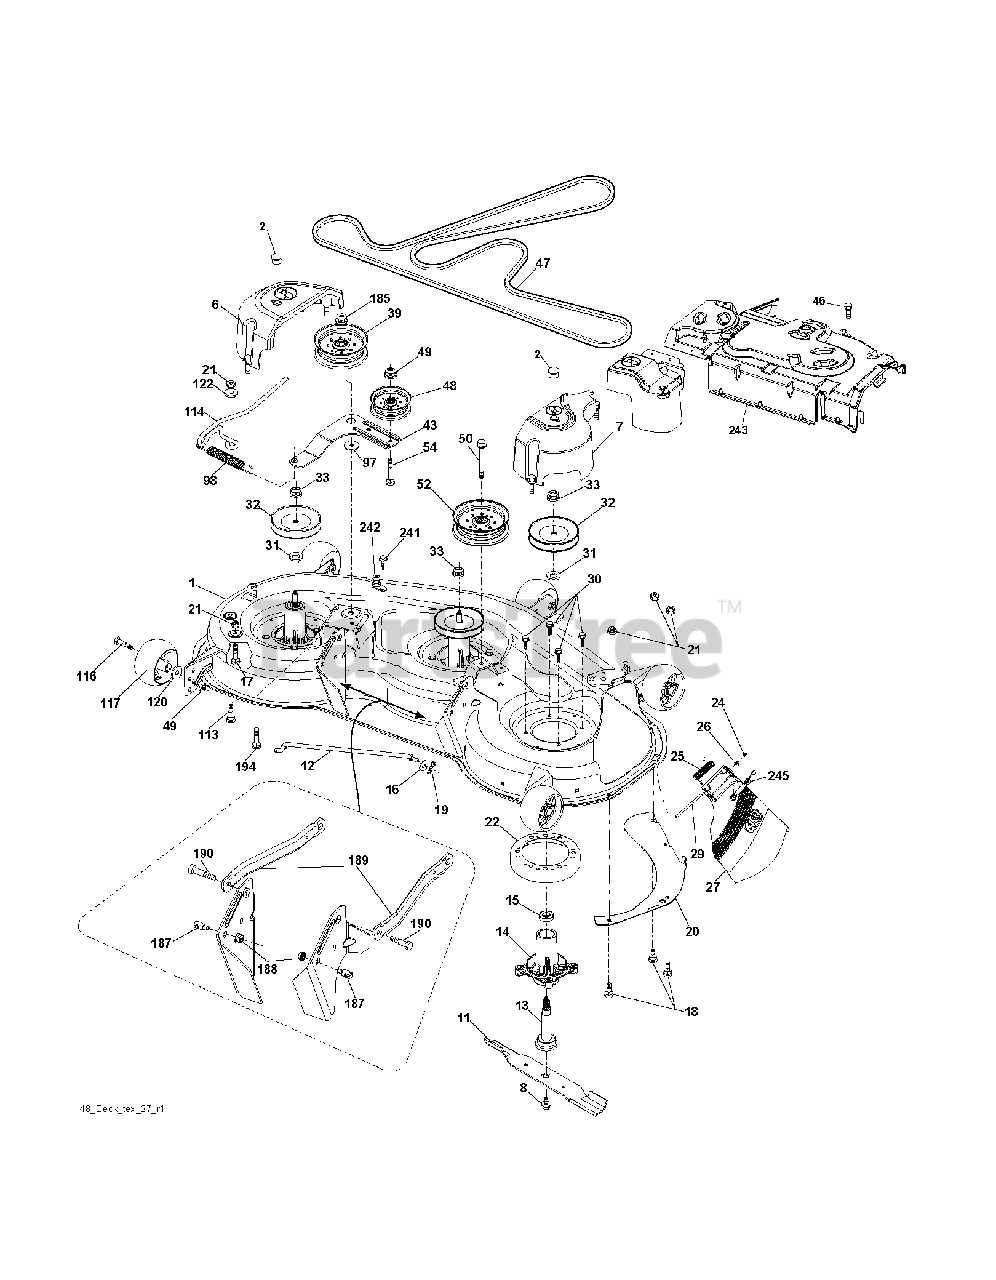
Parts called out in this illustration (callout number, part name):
1	DECK WELDMENT
8	BOLT.WASHER.ASM.7/16-2
11	48" HI-LIFT BLADE
12	ROD.ANTI.SWAY.48/54"K4
13	SHAFT ASM MANDREL
14	HOUSING MANDREL
16	WASHER
17	BOLT
18	BOLT
19	PIN.COTTER.5/16.BOW TI
20	BAFFLE, VORTEX MWR
21	LOCKNUT
22	STRIPPER, MWR ROUND
24	CAP-SLEEVE LT
25	SPRING, TORSION
26	NUT PUSH M
29	ROD.HINGE
30	SCREW, WASHER HEAD
31	WASHER.SPACER.MANDREL
32	PULLEY MANDREL
33	NUT.FLANGE.LOCK.TOP
39	PULLEY.IDLER.4.50/HUB SPECIAL
43	ARM.IDLER
46	SCREW.1/4-20X5/8
47	BELT.DRIVE.DECK
48	PULLEY.IDLER.48"PRIMARY
49	NUT LOCK FLG 3/8-16 UNC
50	SCREW TT 3/8-16X2-1/4 UNC
52	PULLEY.IDLER.2006
54	BOLT.3/8-16X1.50
98	SPRING, DECK DRIVE
113	BOLT CRT
114	ROD.TENSION.RELIEF.TEX
116	BOLT.SHOULDER.3/8-16X3-5/8
117	WHEEL. GUAGE RALLY
122	BUSHING.RELIEF.TENSION
185	NUT.LOCK.FLANGE.7/16
187	STUD.FASTNER.W/ANTI-ROTATE
188	NUT LOCK HEX FLANGE 5/16-18
189	ARM.SUSPENSION.MOWER
190	BOLT.SHOULDER
194	BOLT.CARR.SQNK.7/16
242	PORT.WASHOUT
